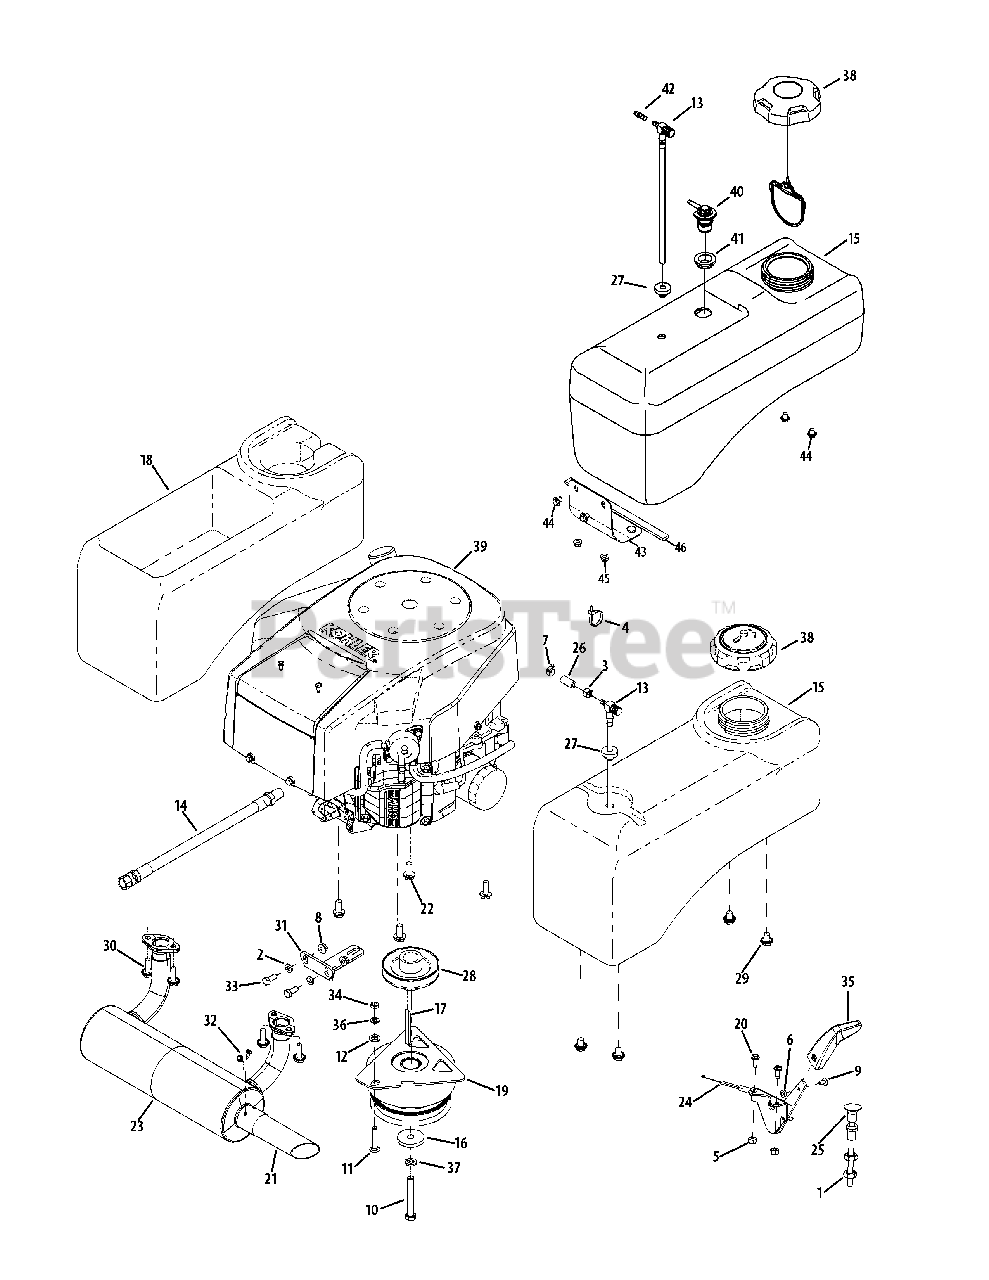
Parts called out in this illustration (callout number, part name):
1	Jam Nut, 3/8-24
2	Washer, .344 x .688 x .063
3	Hose Clamp, .490
4	Cable Tie
5	Nylock Nut, #10-32
6	Nut, #8-32
7	Hose Clamp, .250-.625
8	Flange Counterlock Nut, 5/16-18
9	Machine Screw, #8-32 x .356
10	Hex Screw, 7/16-20 x 3.00
11	Carriage Bolt, 5/16-18 x 1.75
12	Washer, .406 x .750 x .063
13	Fuel Pick-Up Fitting
14	Oil Drain Hose
15	Fuel Tank
15	Fuel Tank Assembly
16	Washer, .438 x 1.745 x .250
17	Bevel Key, .250 x .250 x 2.75
18	Utility Bin
19	PTO
20	Flange Screw, #10-32 x .500
21	Straight Exhaust Pipe
22	Flange Screw, 3/8-16 x .875
23	Muffler
24	Throttle Control Cable
25	Choke Cable
26	Fuel Hose, 1/4
27	Fuel Tank Grommet
28	Transmission Drive Pulley
29	Hex Flange Screw, 3/8-16 x .500
30	Hex Flange Screw, 5/16-18 x 1.0
32	Hex Washer Screw, #10-16 x 0.500
33	Hex Screw, 5/16-18 x .75
34	Jam Nut, 5/16-18
35	Throttle Control Knob
36	Lock Washer, 5/16
37	Lock Washer, 7/16
38	Fuel Cap
39	Kohler SV715-3025 Engine
40	Rollover Valve
41	Rubber Grommet, 23 x 3.55
42	Hose Vent, 3/16 EPA
43	Bracket, Fuel Tank
44	Screw, Hex M10-1.5 x 12.7
45	Nut, Flange Lock 3/8-16
46	Tape, Foam .75" x .25"
